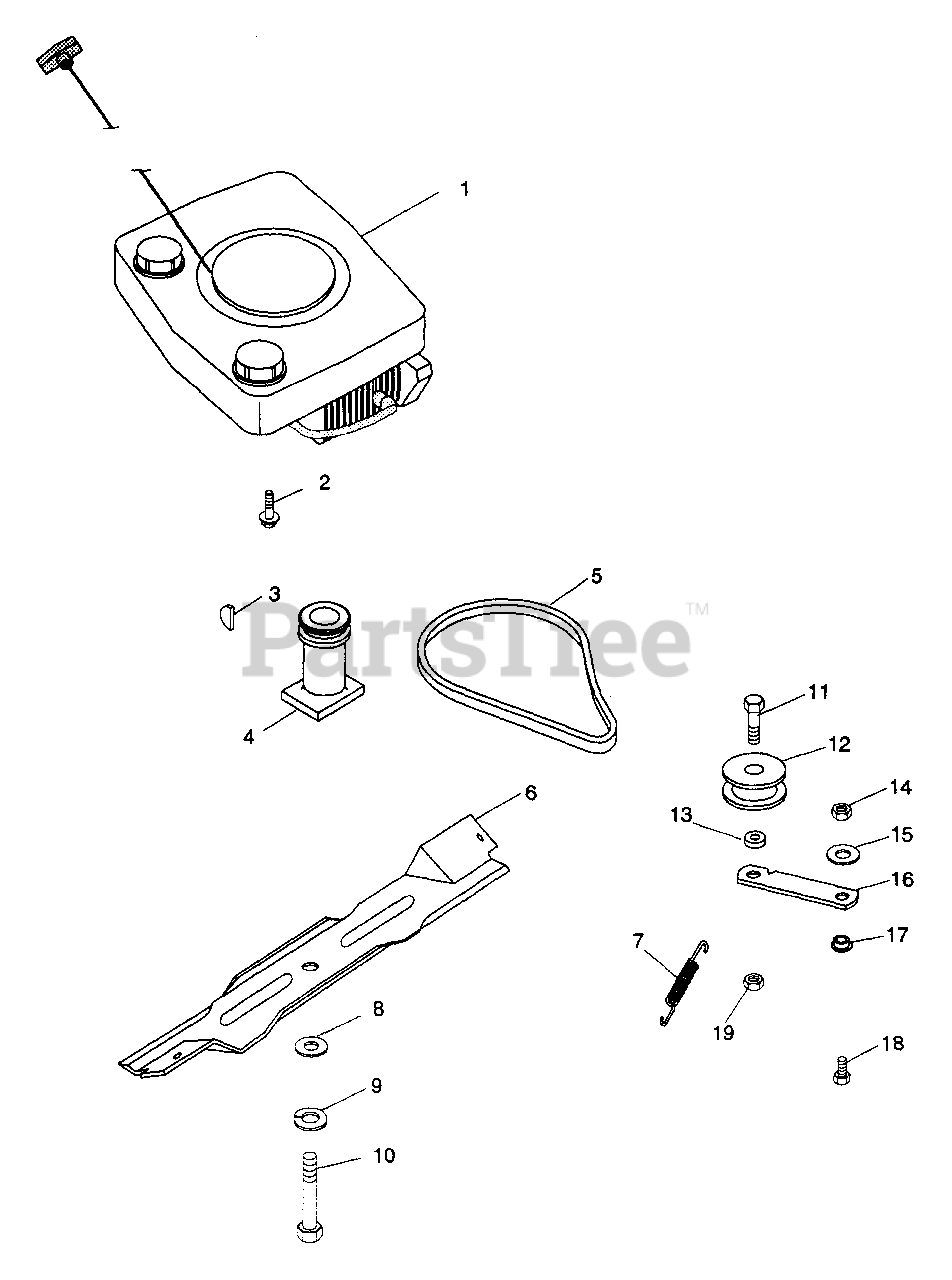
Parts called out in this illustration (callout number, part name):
1	ENGINE B/S 4HP. QUANTUM
1	ENGINE TEC. 4.5HP. RECL. PREM
1	ENGINE TEC. 4HP. RECL. PREMIER
2	SCR-TAP .375-16X1.0 HWH PL TR
3	KEY-WDRF .156X.625X.25 SAE 6
4	BLADE ADAPTER
4	BLADE ADAPTER TECUMSEH
5	V-BELT, 3L-COGGED
6	21" MOWER BLADE
7	SG-TENS .043X.44X3.31 WLD 5.8
8	WSHR-HDND-THR .390X1.50X.125PL
9	WSHR-LK .375X.094 MED PL
10	BLT-HEX .38-24X2.00 PL GR5
11	BLT-HEX .44-14X1.25 PL GR2
12	IDLER-FLAT 1.75 X .47
13	SPACER .52 X .45 X .34
14	NUT-LK .312-18 GR A PL
15	WSHR-FL-STL .323X.625X.062 PL
16	IDLER ARM
17	BSHG-FLG .325X.501X.250X1.120
18	BLT-HEX .31-18X.75 PL GR2
19	NUT-LK .437-14 GR A PL
